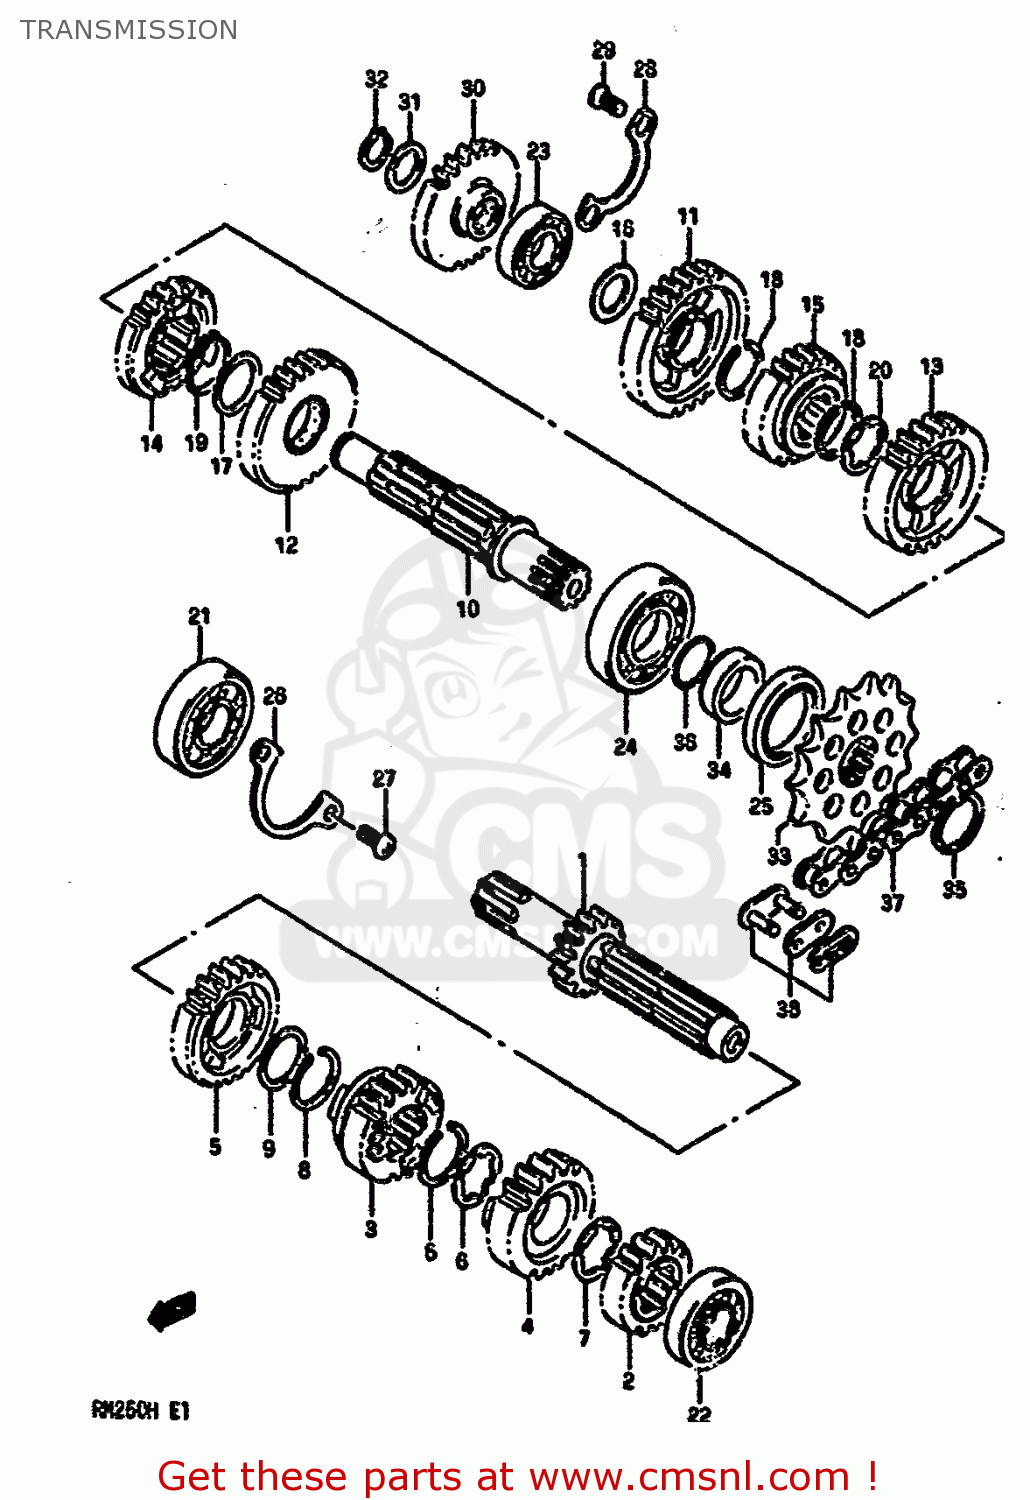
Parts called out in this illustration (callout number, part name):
1	SHAFT,COUNTER
2	GEAR,2ND DRIVE
3	GEAR,THIRD DRIVE
4	GEAR,FOURTH DRIVE
5	GEAR,5TH DRIVE
6	WASHER,LOCK
7	WASHER,LOCK
8	CIRCLIP
9	SHIM(22X28X0.5)
10	SHAFT,DRIVE
11	GEAR,FIRST DRIVEN
12	GEAR,SECOND DRIVEN
13	GEAR,THIRD DRIVEN
14	GEAR,FOURTH DRIVEN
15	GEAR,FIFTH DRIVEN
16	WASHER
17	SHIM
18	CIRCLIP
19	CIRCLIP,25MM
20	WASHER,LOCK
21	BEARING(20X52X15)
22	BEARING(17X40X12)
23	BEARING(17X40X12)
24	BEARING
25	SEAL,OIL(32X42X6)
26	PLATE,COUNTERSHAFT BEARING
27	SCREW 6X12
28	PLATE,DRIVESHAFT BEARING
29	SCREW
30	GEAR,KICK STARTER IDLE
31	WASHER
32	CIRCLIP
33	SPROCKET,ENGINE
34	SPACER(22X32X9.5)
35	CIRCLIP
36	O RING(D:1.7,ID:22)
37	CHAIN ASSEMBLY,DRIVE
38	JOINT ASSEMBLY,CHAIN
